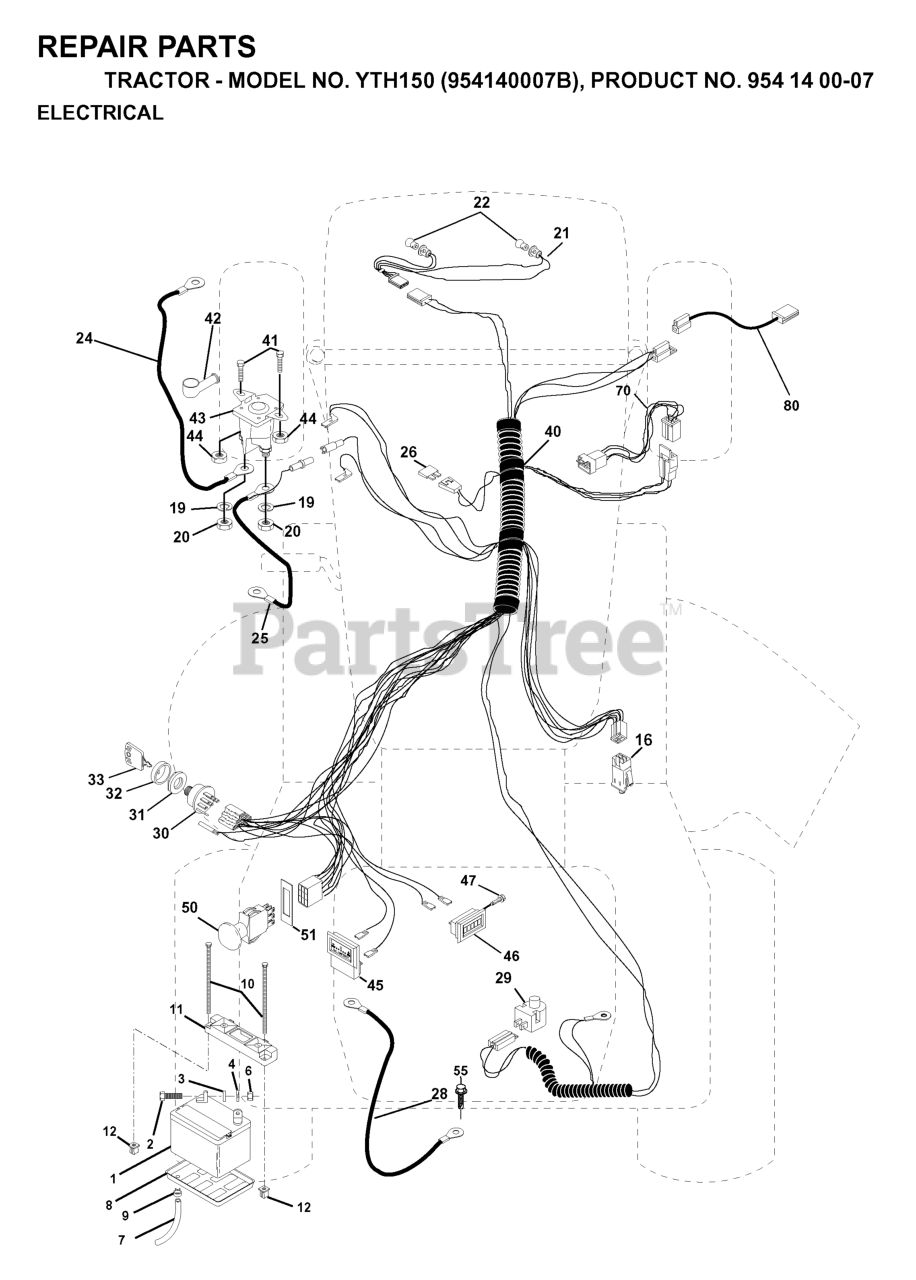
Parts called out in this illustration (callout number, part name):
1	BATTERY 12 VOLT 25 AMP
2	BOLT.HEX.1/4.X.3/4.DICHROMATE
4	LOCKWASHER
6	NUT
7	PLASTIC TUBE
8	BATTERY TRAY T
9	HOSE CLAMP T
10	BOLT 1/4-20 X 7.5
11	BATTERY HOLDDOWN FRONT MOUNT
12	NUT, PUSH NYLON 1/4" BATTERY
16	SWITCH INTERLOCK
19	LOCKWASHER
20	NUT
21	HARNESS LIGHT SOCKET
24	BATTERY CABLE GT
25	CABLE BATTERY 6 GA 22" W/16W
28	CABLE GROUND 6 GA 21" 90T BLK
29	RP.SWITCH.PLUNGER.NC.GRAY
30	SWITCH.IGNITION.4.POSITION
31	NUT IGNITION
32	COVER SWITCH KEY
33	KEY.MOLDED.GENERIC
40	IGN HARNESS
41	BOLT
42	TERMINAL COVER
43	SOLINOID
44	Nut, Keps Blk Hex 1/4-20 UNC
45	AMMETER
46	HOUR METER T
47	Screw 10-24 x 1/2 Black
50	SWITCH PTO 3 PDT
51	FRAME RETAINING RING
55	Screw 5/16-18 x 1/2 Hex, Self Tapping 5/16-18 x 1/2
70	HARNESS ENG. KOHLER
80	HARNESS, CLUTCH
